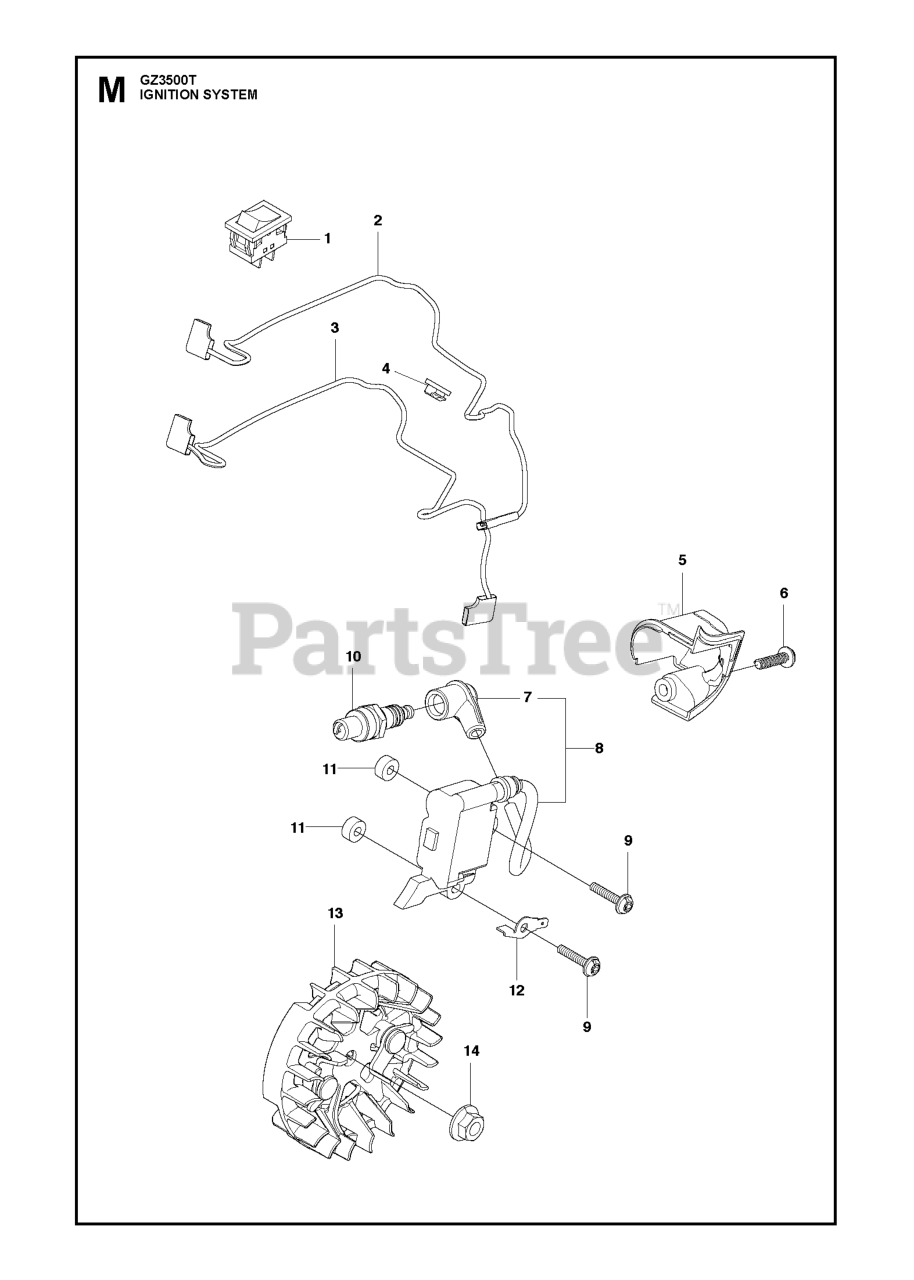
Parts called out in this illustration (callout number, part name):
1	STOP SWITCH NM_09091801
2	CORD, SWITCH
3	CORD, EARTH
5	COVER SPARK PLUG BLACK
8	IGNITION COIL ASSY
9	BOLT M4X20
10	SPARK PLUG
12	TERMINAL
13	FLYWHEEL ASSY
14	NUT
